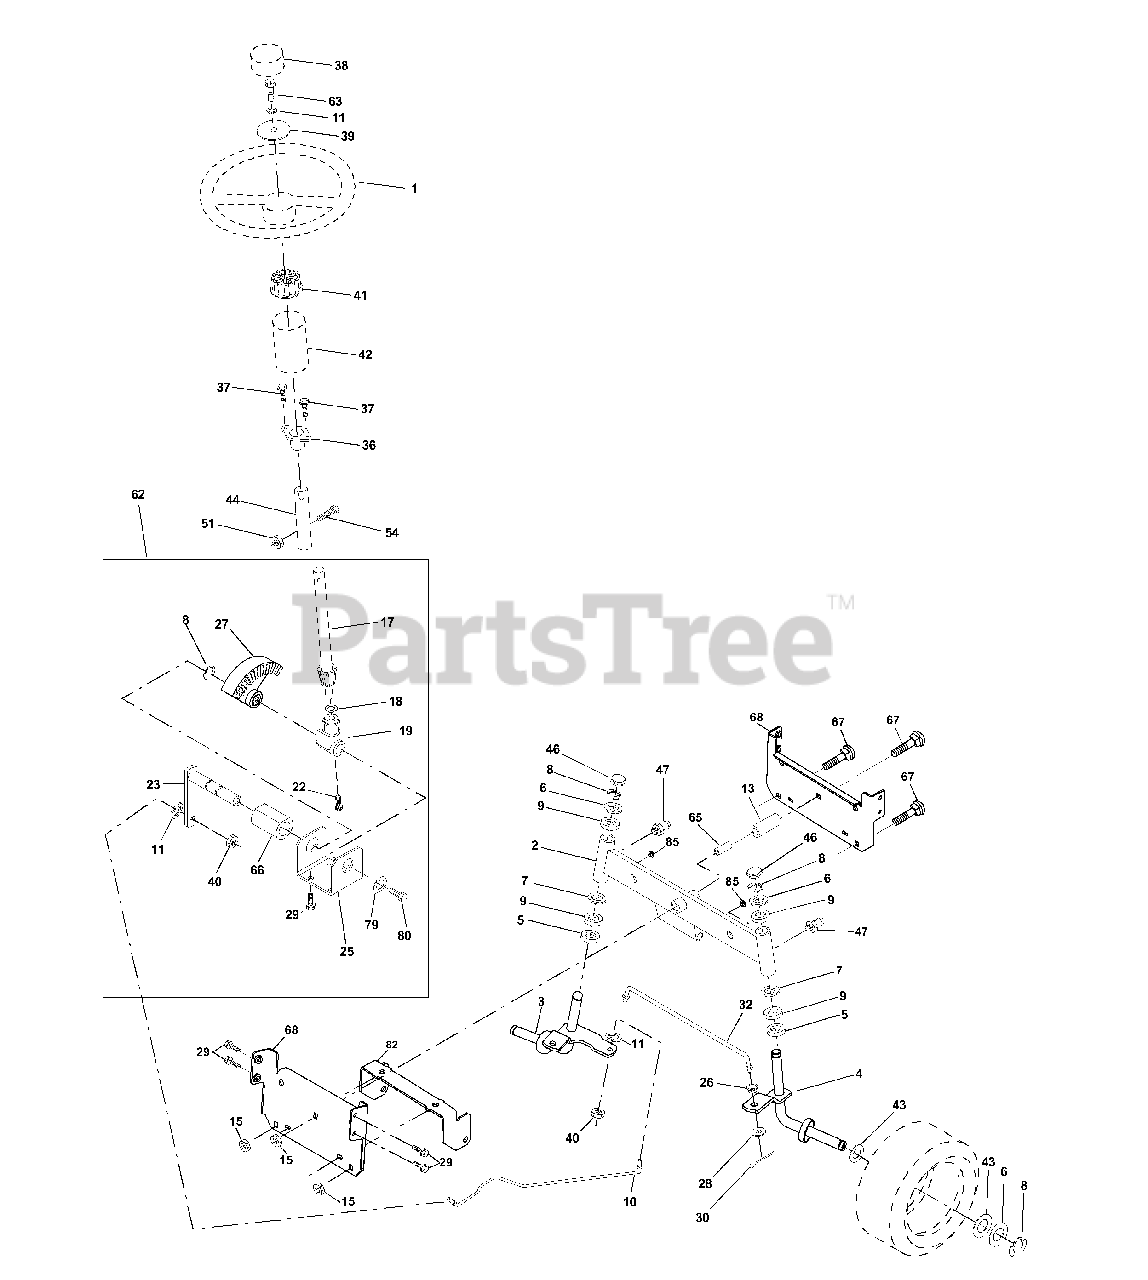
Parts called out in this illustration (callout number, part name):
1	Wheel Steering Auto Black
2	Axle Asm Front
3	Spindle Asm Lh
4	Spindle Asm Rh
5	Bearing Race Thrust Harden
6	Washer 25/32 X 1 5/8 X 16ga
7	Washer 27/32 X 1 1/4 X 16 Ga
8	Ring Klip #t5304-75
9	Bearing Col Strg Blk
10	Link Drag Extended
11	Lockwasher
13	Spacer Bearing Axle Front
15	Hex Flange Lock
17	Shaft Asm Strg 5/8 X 15 19 Lt
18	Washer Thrust 515x 750x 033
19	Support Shaft
22	Screw Hex Wsh Hd Torx
23	Shaft Asm Pittman
25	Bracket Steering
26	Bushing Rod Tie Blk Lt
27	Gear Sector
28	Washer 13/32 X 7/8 X 16ga
29	Screw 3/8-16x3/4
30	Pin
32	Rod Tie Wire Form 19 75 Mech
36	Bushing Strg 5/8 Id Dash
37	Screw TT #10-32 x 5 x 3/8 Flange
38	Insert Cap Strg
39	Washer 13/32 x 2-3/8 x 12Ga
40	Locknut Center
41	Adaptor Wheel Strg 640/ 635id
42	Boot Dash Steering
43	Washer 25/32 X 1 1/4 X 16 Ga
44	Extension Steering Non-Adjust
46	Cap Spindle Fr Top Blk
47	Fitting Grease
51	Nut Lock Hex W/Ins.
54	Bolt Fin Hex 5/16-18 Unc P
62	Kit Steering Assembly Service
63	Bolt Fin Hex 3/8-16unc x Gr. 5
65	Spacer Brace Axle
66	Bearing Arm Pittman
67	Bolt Rdhd Sq 3/8-16 Unc x 2-3/4
68	Brace Axle
79	Washer 13/32 x 1-1/4 x 12 Ga
80	Bolt Hex Nylon 3/8-16 x 3/4
82	Bracket Susp Chassis Front
85	Fastener Christmas Tree
